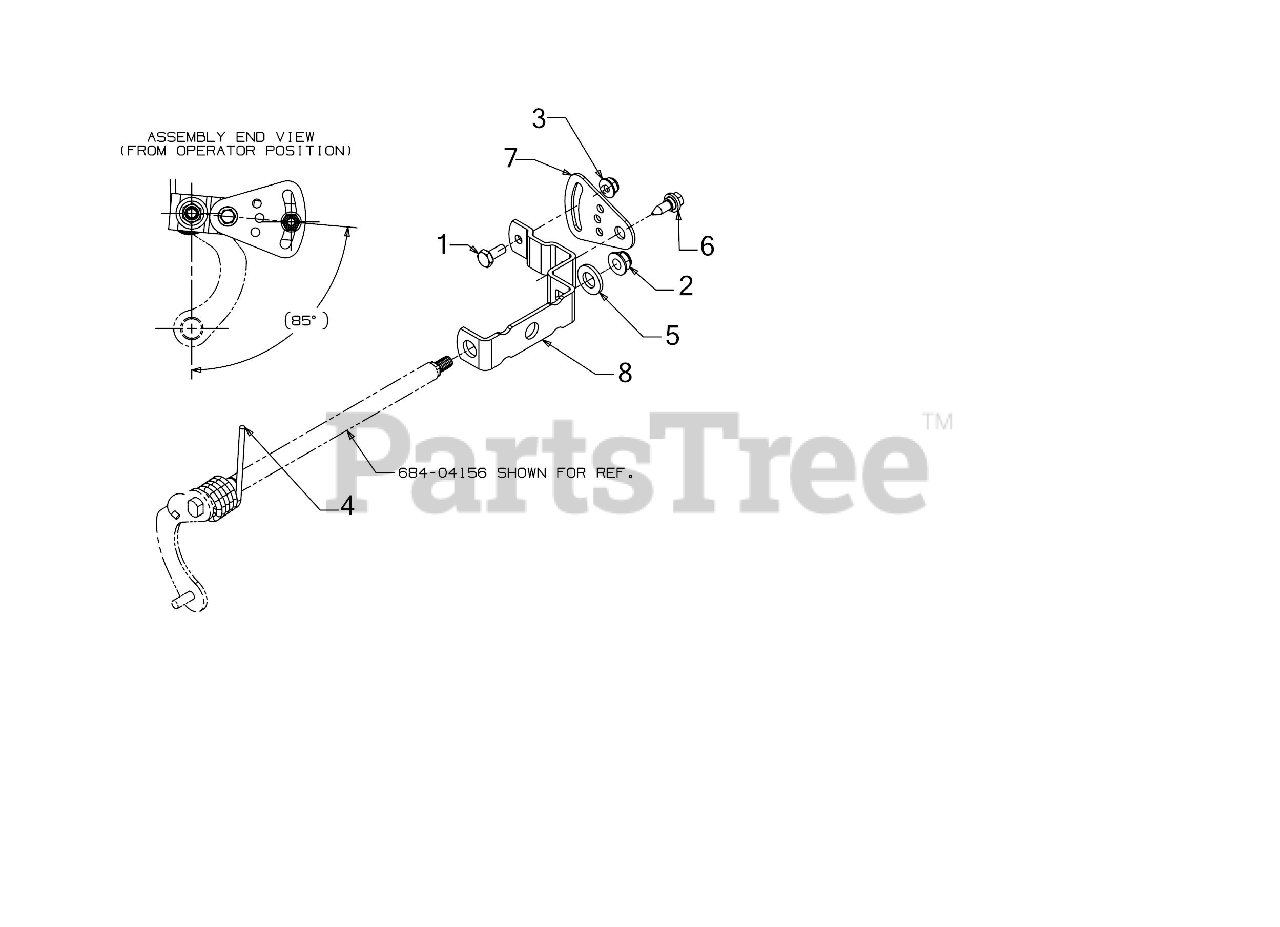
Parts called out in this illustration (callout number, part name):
1	SCREW 1/4-20 x .620 GR5
2	FLANGE LOCK NUT 5/16-18
3	FLANGE LOCK NUT
4	TORSION SPRING
5	FLAT WASHER
6	SHOULDER SCREW
7	PIVOT BRACKET
8	SHIFT SPEED BRACKET
